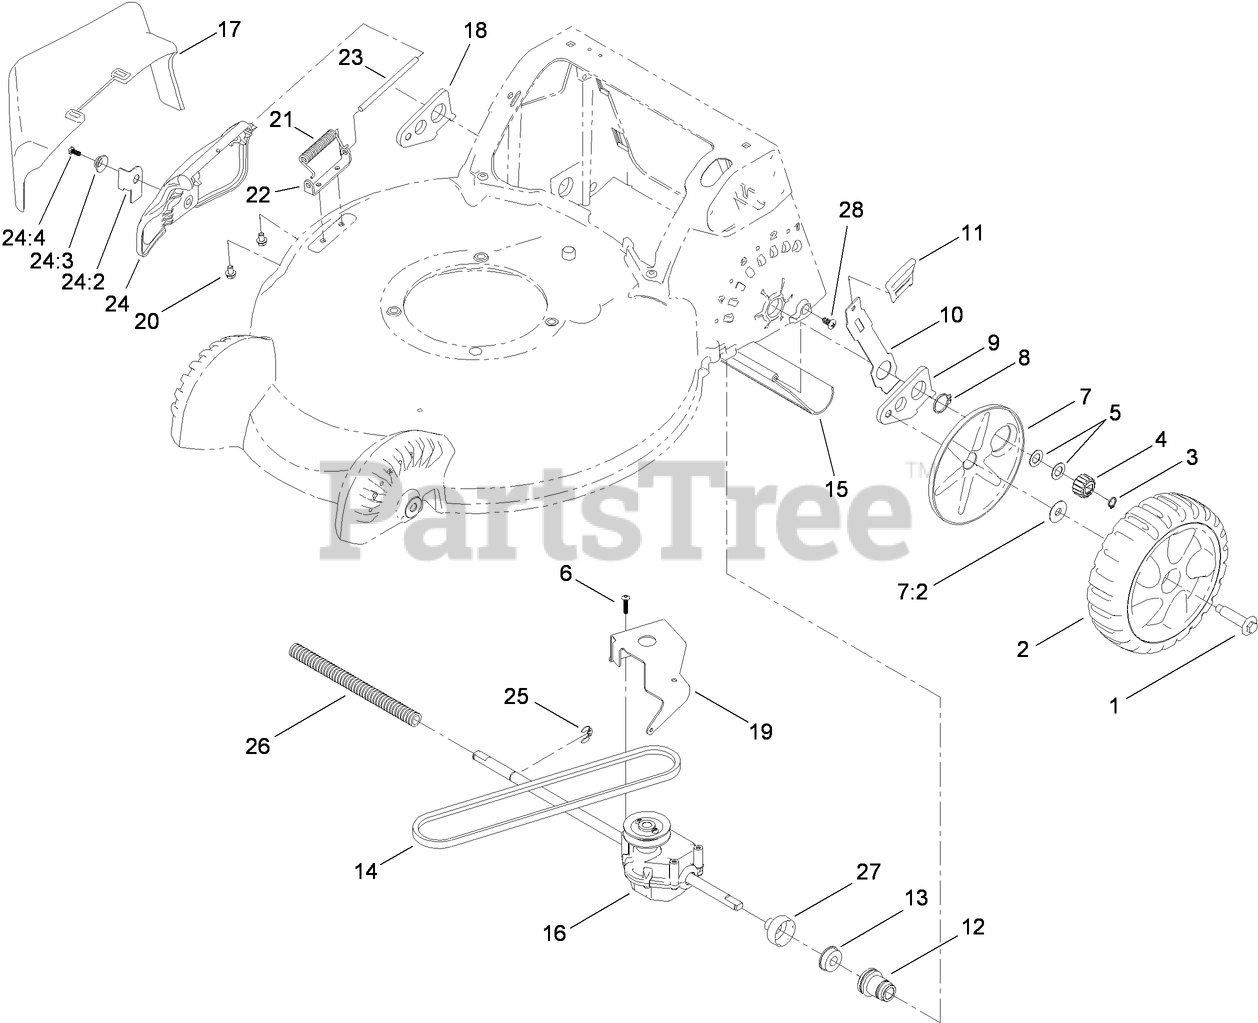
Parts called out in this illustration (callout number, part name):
1	BOLT-SHOULDER
2	REAR WHEEL ASM
3	RING-RETAINING
5	WASHER-PLAIN
6	SCREW-PLASTITE
7:2	WASHER-STEPPED
8	RING-RETAINING
9	ARM-REAR PIVOT, LH
10	ARM-SPRING, REAR
11	KNOB-HOC
12	RETAINER-BEARING
13	BEARING-BALL
14	V-BELT
17	CHUTE-DISCHARGE, SIDE
18	ARM-REAR PIVOT, RH
19	BRACKET-TRANSMISSION
20	SCREW-HWH
21	SPRING-TORSION
22	BRACKET-COVER
24	DISCHARGE DOOR ASM
24:2	LATCH-DOOR
24:3	CAP-DOOR
24:4	SCREW-PLASTITE
25	RING-RETAINING,CLIP
26	CONDUIT-CONVOLUTED, SPLIT
27	CAP-BEARING
28	SCREW-PTH
